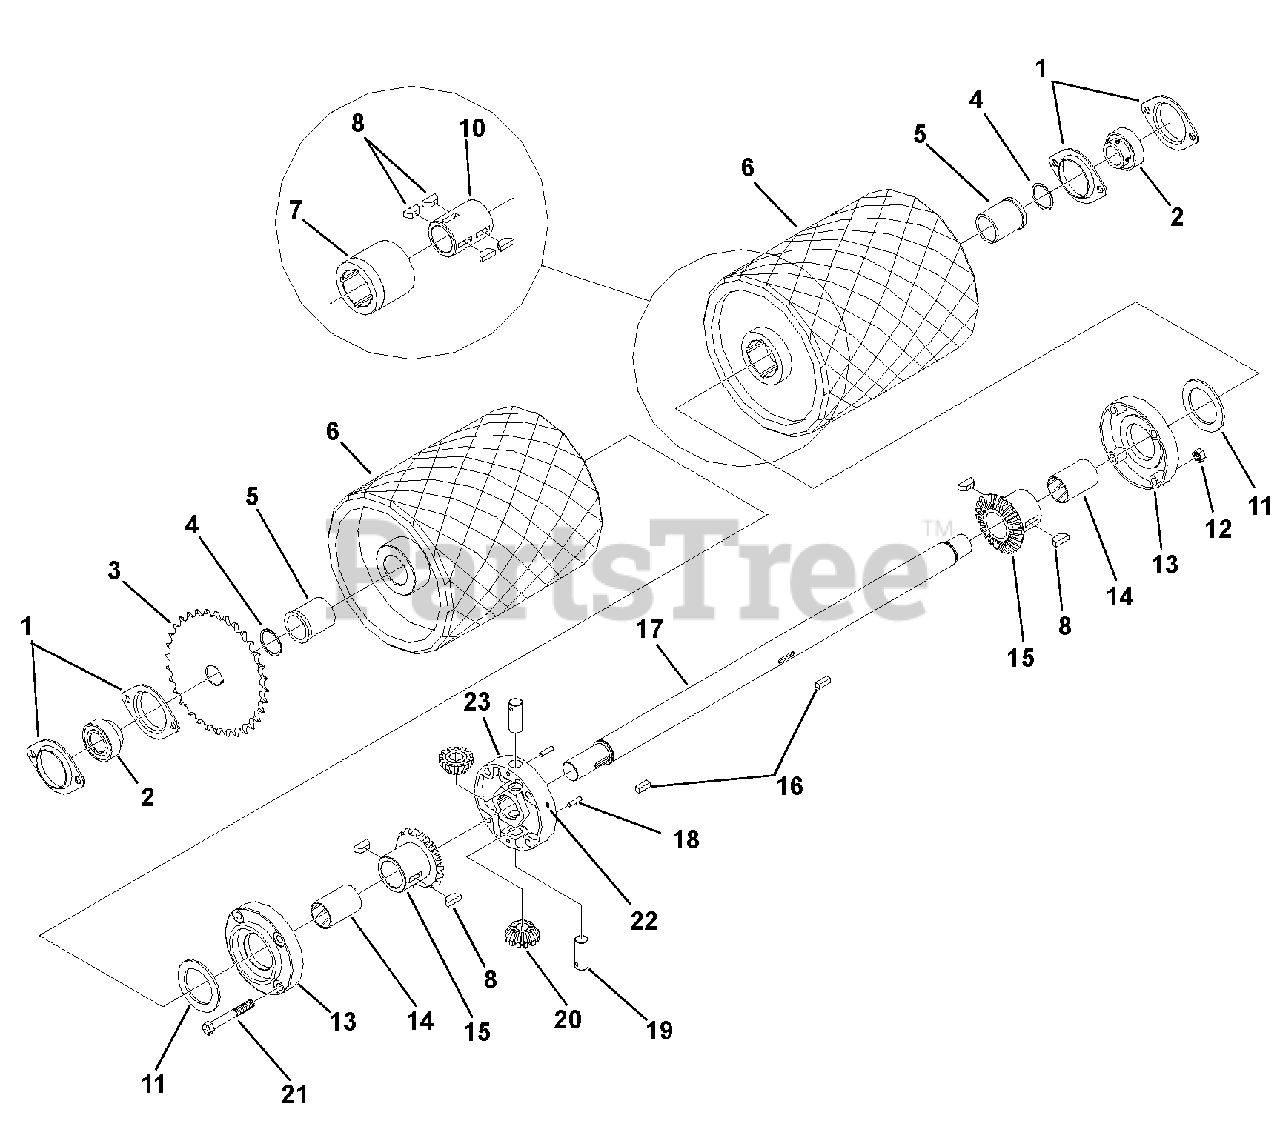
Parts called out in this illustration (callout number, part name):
1	Bearing Flange
3	Sprocket, 40-Tooth
4	Snap Ring, Axle
6	Roller, Traction
7	Roller, Extension (995033, 035)
8	Key, Woodruff .25 x .875 (995030, 032)
9	Key, Woodruff .25 x .875 (995033, 035)(995033, 035)
10	Sleeve, Keyed (995033, 035)
12	Nut, Hex .38-24
13	Plate, Side
15	Gear, Differential Axle With Bushing
16	Key, Square .25 x .25 x .75
17	Axle, 25-Inch (995030, 032)
18	Pin, Groove .187 x 1
19	Shaft, Differential Pinion
21	Cap Screw, Hex Head .38-24 x 2.75
22	Grease Fitting .25-28
23	Plate, Center
